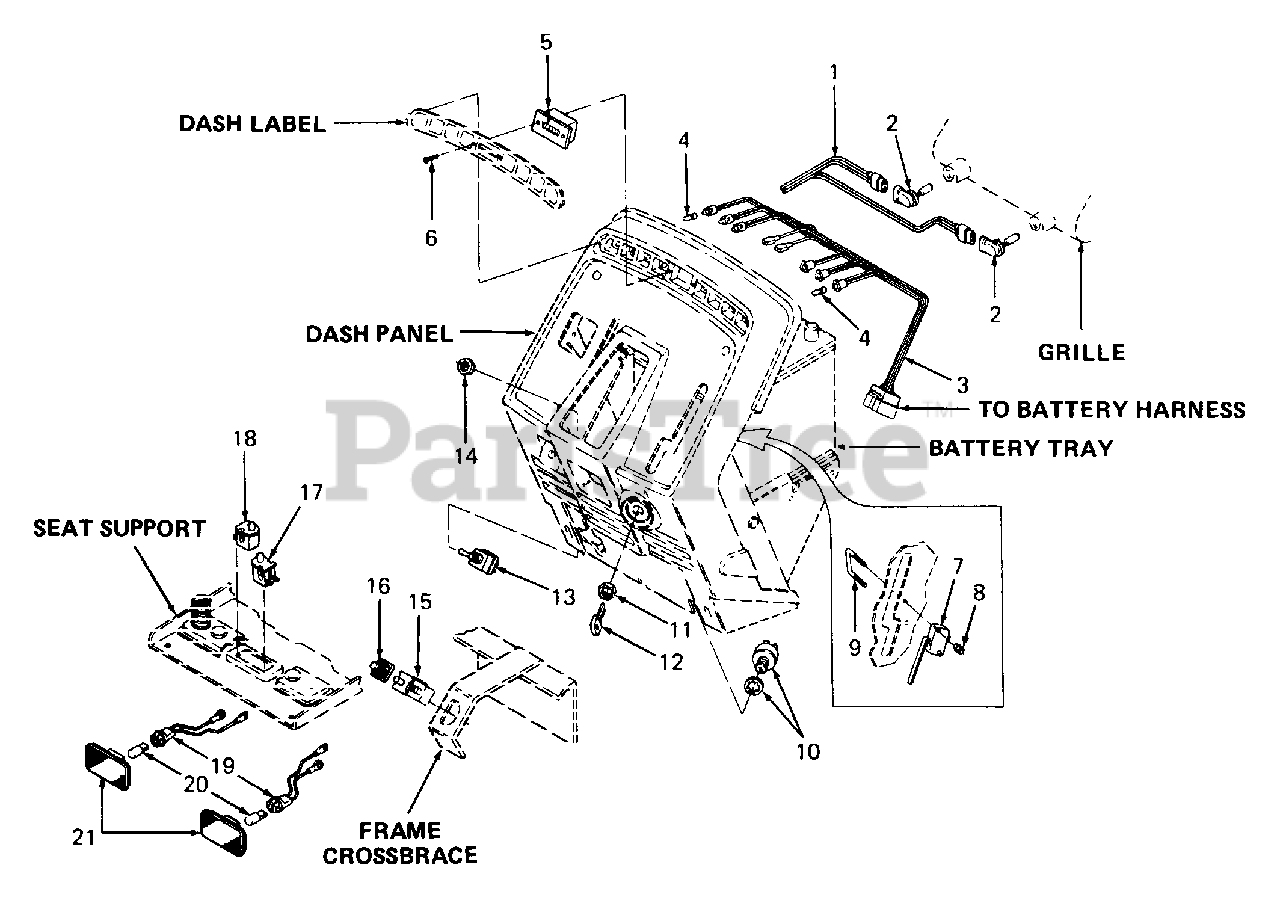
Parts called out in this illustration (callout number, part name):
1	Harness, Main Wire
2	Bulb, Head Lamp
3	Harness, Indicator Wire
4	Bulb, Indicator
5	Hour Meter
6	Screw, Truss Hd Tapp, #6 X .62 Lg
7	Switch, Reverse
8	Nut, Hex Insert Lock, #4-40
9	Screw, Switch
10	Switch, Ignition
11	Nut, Ignition Switch
12	Key, Ignition
13	Switch, PTO
14	Nut, Hex, 1/2-27 X .100 Thk
15	Switch, Interlock
16	Boot, Switch
17	Switch, Snap Mount - Normally Closed (Grey)
18	Switch, Snap Mount - Normally Open (Black)
19	Cable Assy, Tail Light
20	Bulb, Tail Light
21	Lens Assy, Tail Light
